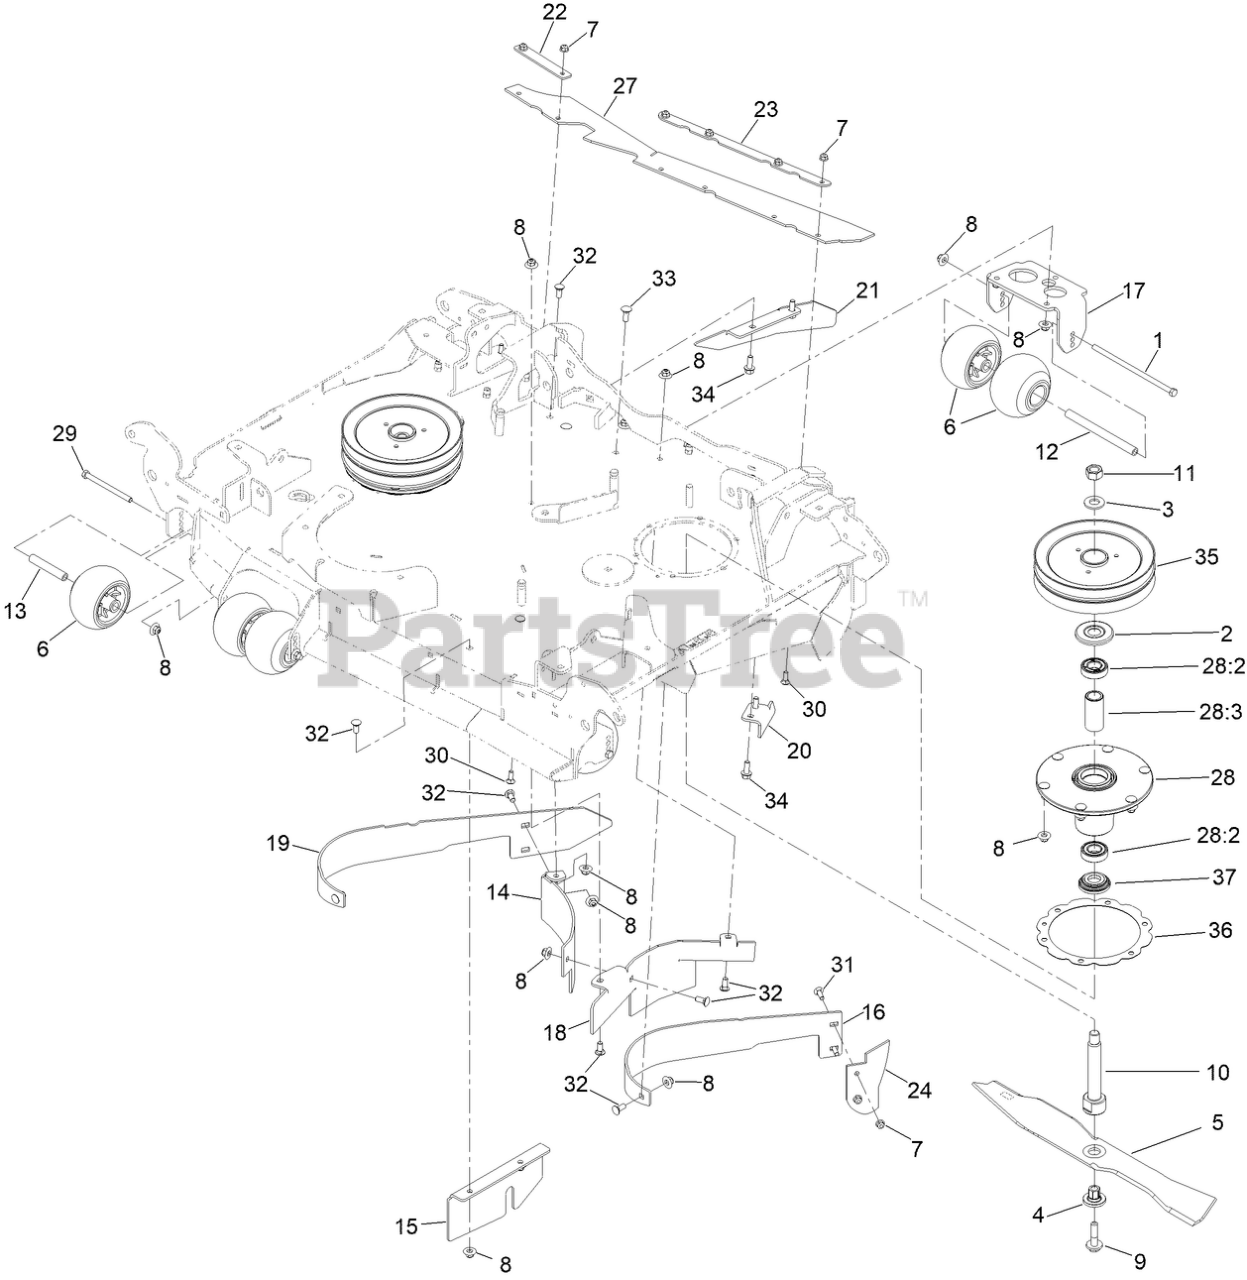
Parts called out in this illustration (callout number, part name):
1	SCREW-HH
2	GUARD-BEARING, TOP
3	WASHER
4	BUSHING-HEX
5	BLADE-24.50 MULCH
6	ROLLER-SCALP, ANTI
7	NUT-HF, NI
8	NUT-FLANGE, NI
9	SCREW-SEMS
10	SHAFT-SPINDLE
11	NUT-HEX
12	SPACER-WHEEL
13	SPACER-WHEEL SHORT
14	BAFFLE-CENTER, REAR (RH)
15	PLATE-BLOCK, FRONT
16	BAFFLE-DOGLEG, CENTER (LH)
17	BRACKET-ANTISCALP, REAR
18	BAFFLE-CENTER
19	BAFFLE-DOGLEG, CENTER (RH)
20	BAFFLE-BREAKER
21	PLATE-FIN, DISCHARGE
22	SUPPORT-FLAP, LH
23	SUPPORT-FLAP, LH
24	GUARD-DISCHARGE
27	FLAP-DISCHARGE
28	SPINDLE ASM
28:2	BEARING-BALL
28:3	SPACER-BEARING
29	SCREW-HH
30	SCREW-CARR
31	SCREW-CARR
32	BOLT-CARR
33	BOLT-CARR
34	SCREW-HHF
35	SHEAVE-DOUBLE BLADE DRIVE
36	RING-SPACER, HOUSING
37	GUARD-BOTTOM
